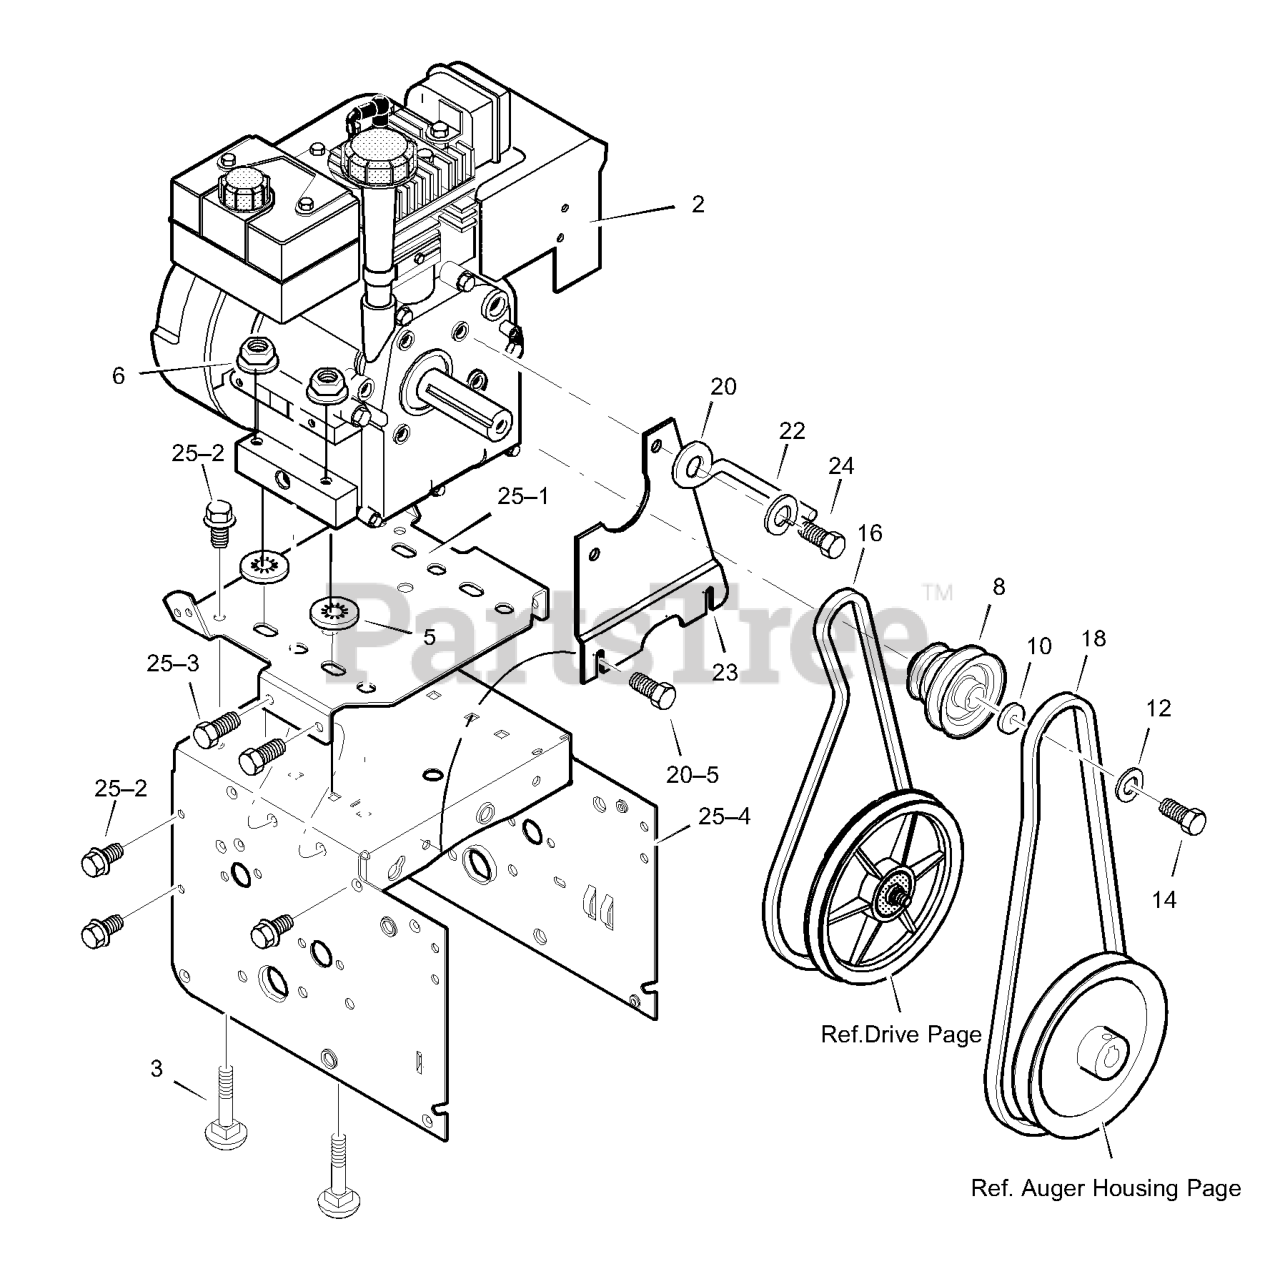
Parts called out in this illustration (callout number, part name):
2	ENGINE
3	BOLT, CARRIAGE 5/16-18
5	RETAINER, PUSH
6	NUT, HEX 5/16-18
8	PULLEY, ENGINE
10	WASHER
12	WASHER .38ID
14	SCREW, 3/8-24 x 1.00
16	BELT, V 3L 33.13LG
18	BELT, V 4L 38.1MF16" 5-10
20	GUIDE, BELT
22	WASHER, SPTLK .31X.58X.08
23	PLATE, ANTI VIBRATION
24	SCREW, 5/16-24 x 1.00
25	FRAME ASSEMBLY
25-1	PLATE, ENGINE MOUNT
25-2	SCREW, TAP 1/4-20 X .63
25-3	SCREW, TAP 5/16-18 X .50
25-4	FRAME, MOTOR BOX
